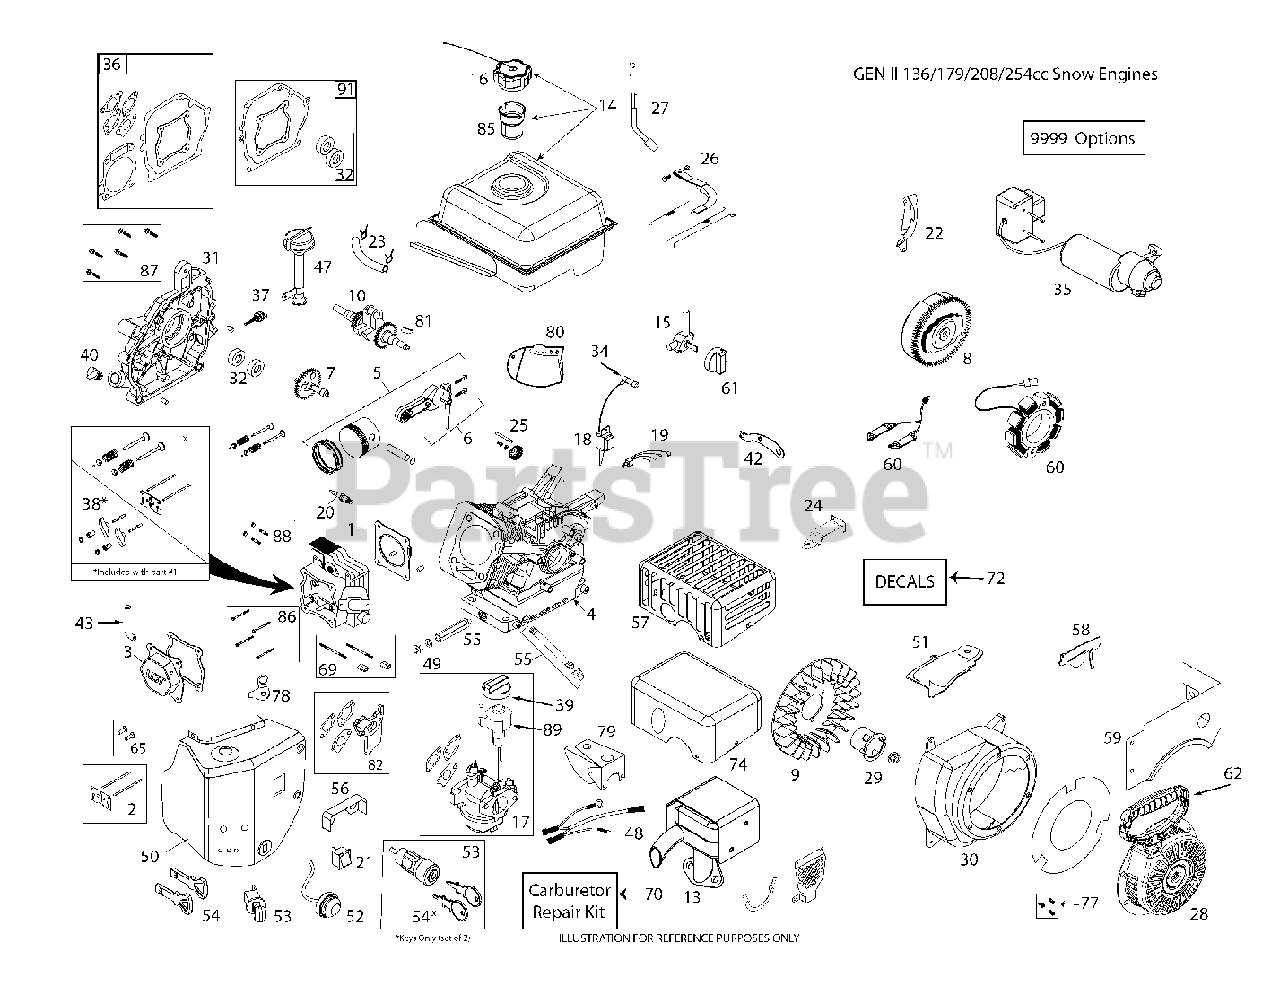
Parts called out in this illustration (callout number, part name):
2	KIT.PUSH.ROD.SRV(SK208-1001)
3	VALVE COVER ASSEMBLY
4	CYLINDER.ASM.SKSN0001.2
8	FLYWHL.ASSY.MANUL.SK2081700
9	KIT.COOLNG.FAN.SERV(SK208-4000
10	CRANKSHAFT KEYED LCT 179
13	ASSY.MUFFLER.GENII.SKSN0201.1
14	FUEL.TK.ASSY.GENII.SKSN0311.1
15	FUEL.PETCOCK.SNOW(SKSN4900)
16	FUEL CAP OVERSIZED CLICK STYLE
17	Carburetor, L17D Gen 2 Lct 179
18	COIL.ING.CDI.HI TEMP.SKSNO416.
20	SPARK.PLUG(2083810)
22	FLYWHEEL SHIELS.LCT 136 MANUAL
23	FUEL HOSE KIT
24	SPEED.CTRL.BRKT.(SKSN0150)
25	GOVENOR.GEARS ASM(SK2082900)
26	CARBURETTOR GOVERNOR LINK.ASM.
27	KIT.GOVERNOR.CRANK(SK208-3100)
28	RECOIL.STRT.ROUND(BLK) SNOW
29	STRTER.CUP(NON-SLOT)SKSN0601.2
30	BLOWER HOUSING LCT 179
31	CRANKCASE.CVR.PRESS.IN.HI-OIL.
32	SEAL KIT (2 PCS)
34	SPARK.PLUG.BOOT.SNW,SKSN4691.1
36	GASKET KIT ENGINE LCT 208
37	DIPSTICK SMALL
38	ROCKER ARM KIT
39	CHOKE.KNOW.SNOW(SKSN4500)
40	NON REMOVABLE PLUG
43	TUBE.BREATHER.LCT.208
47	High Oil Fill Tube Assembly
49	KIT.OIL.DRAIN.PLUG(SK2089911
50	HEATER.BOX.ASY-GEN2
52	PRIMER.BULB.WITH HOSE (SNOW)
53	SWITH.KEY.ASSEM.SNOW.SINGLE.ST
54	KEY SET(2 KEYS) SKSN0407.1
55	OIL PIPE DRAIN LCT 254
57	ASSY.MUFFLER.GENII.SKSN0201.1
58	GOVERNOR.LINK.SHIELD PLATE
59	FUEL.TNK.SKRT.GENII.SKSN0103.1
61	FUEL KNOB-SNOW
62	SNOW.STARTER.CHIP(SKSN-0603)
65	TAPPET.KIT.LCT.208CC
69	CARB.STUDS & COUPLING KIT.SNOW
70	Carburetor Repair Kit, LCT SK9900
74	Muffler Heat Shield Cover
77	Recoil Bolt Kit, LCT
79	COVER.CARBURETOR.SNOW
81	KEYS.FLYWHEEL.208/414CC.5PACK
82	Carburetor Spacer, 208cc Lct
85	Fuel Tank Strainer, LCT 208cc
86	KIT.BOLT.CYLINDER.HEAD.(4PC)
87	KIT.BOLT.CRANKCASE.COVER.6PC
88	STUD.MUFFLER.KIT.LCT
89	Speed Knob, LCT Sksn5325.1
91	Crankcase Cover Gasket
9999	High Altitude Jet for Beyond 6,000 Feet
